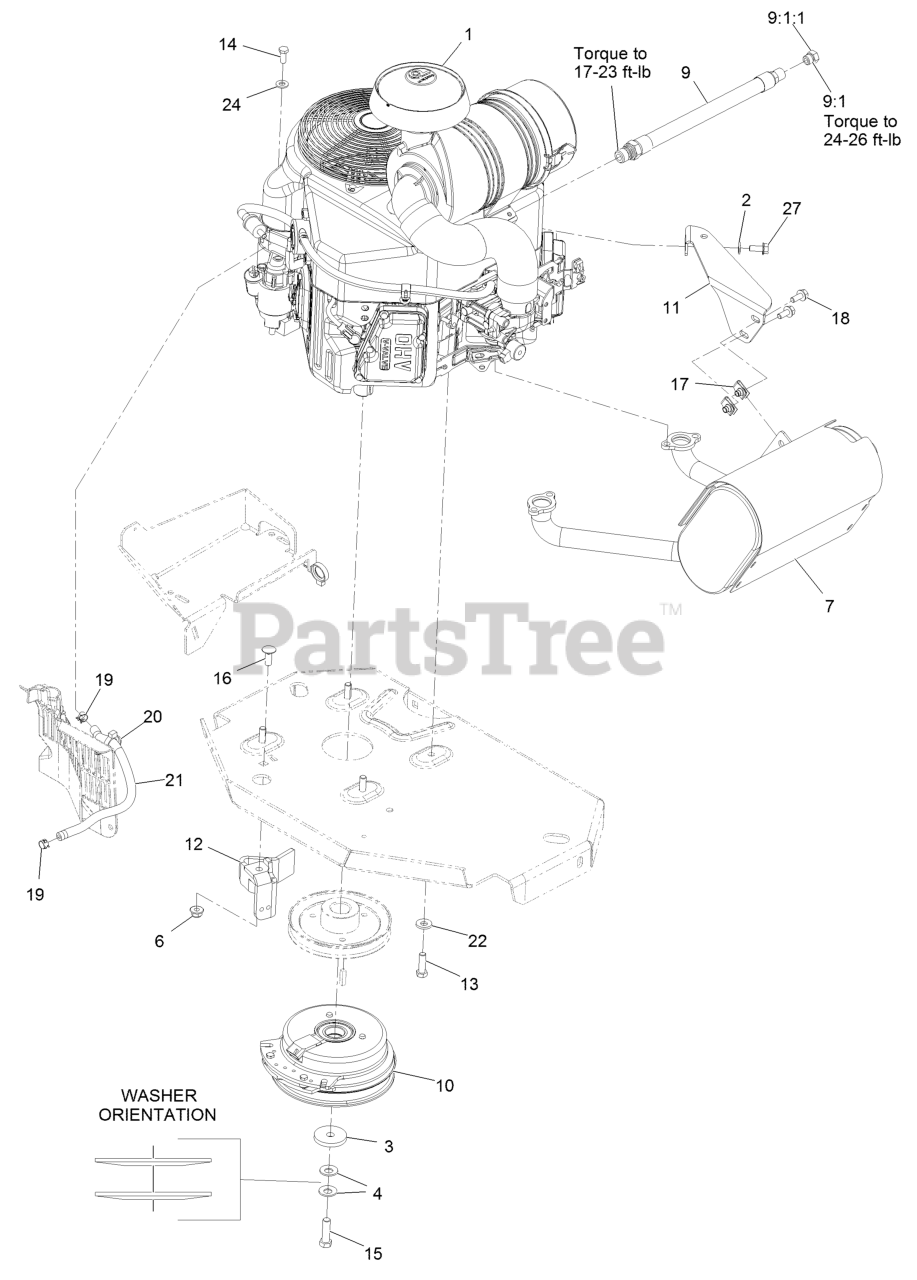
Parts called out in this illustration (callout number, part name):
2	WASHER-SPRING
3	WASHER-CLUTCH
4	WASHER-SPRING
6	NUT-HF, NI
7	MUFFLER
9	ENGINE OIL DRAIN HOSE ASM
9:1	PLUG-HH
9:1:1	O-RING
10	CLUTCH KIT
11	BRACKET-MUFFLER
12	CLUTCH-ANCHOR
13	SCREW-HH
14	SCREW-HH
15	SCREW-HH 7/16-20 X 1 1/2 W/LOCTITE
16	SCREW-CARR
18	SCREW-HHF
19	CLAMP-HOSE
20	CLAMP-HOSE
21	HOSE-FUEL
22	WASHER-BELLEVILLE
24	WASHER-PLAIN
27	SCREW-HHF
